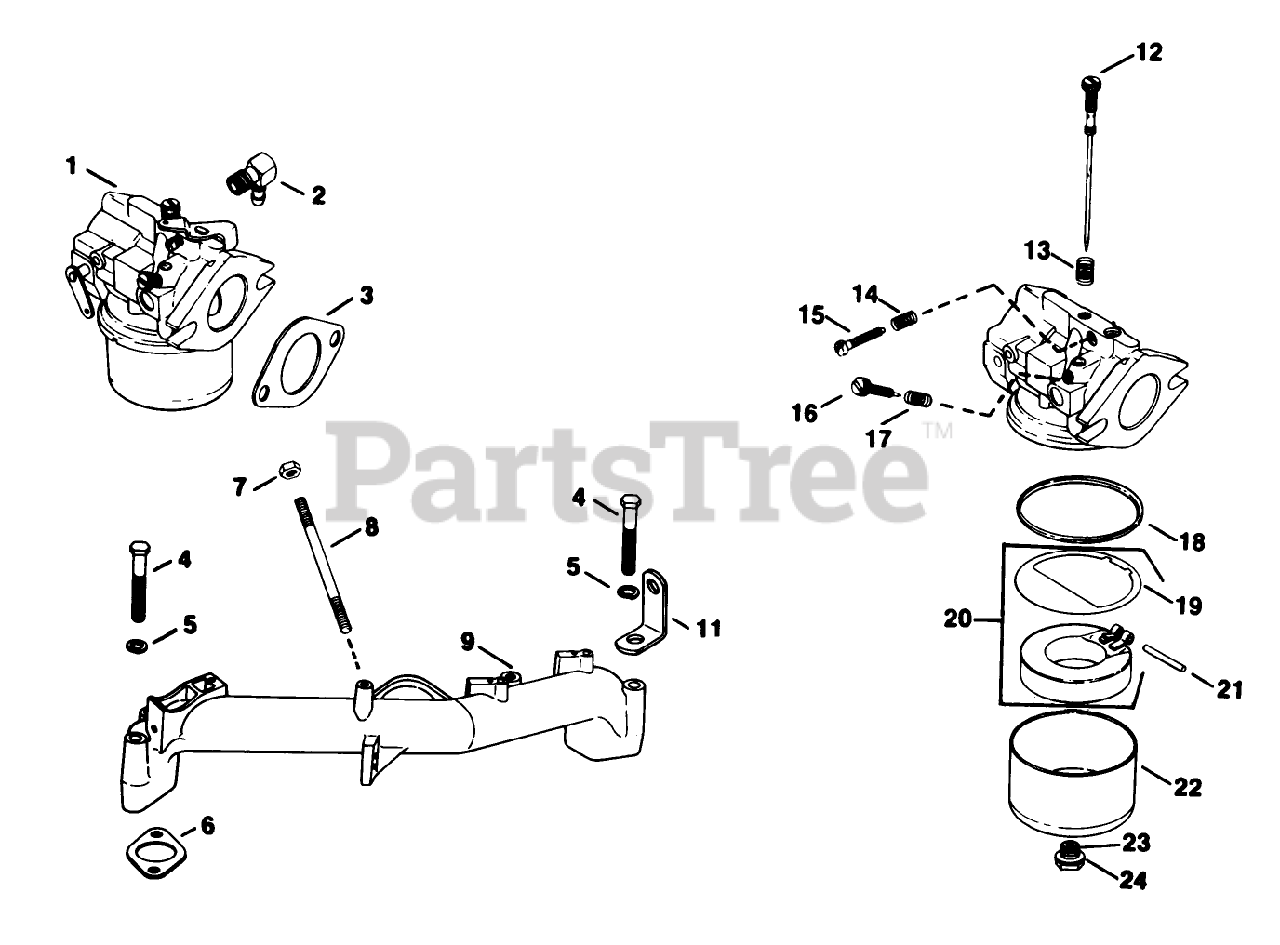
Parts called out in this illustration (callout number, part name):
1	Carburetor Assembly
2	Connector-90?
3	Gasket
4	Screw-H.C.
5	Washer
6	Gasket-Intake
9	Manifold-Intake
11	Strap-Lifting
12	Needle-Main Fuel Adj.
13	Spring-Main
14	Spring-Idle Speed
15	Screw
16	Needle-Idle Adj.
17	Spring-Idle
18	Gasket-Bowl
19	Gasket-Bowl Baffle
20	Kit-Float
21	Pin-Float Hinge
22	Bowl
23	Screw-Bowl Retainer
24	Gasket-Bowl Screw
